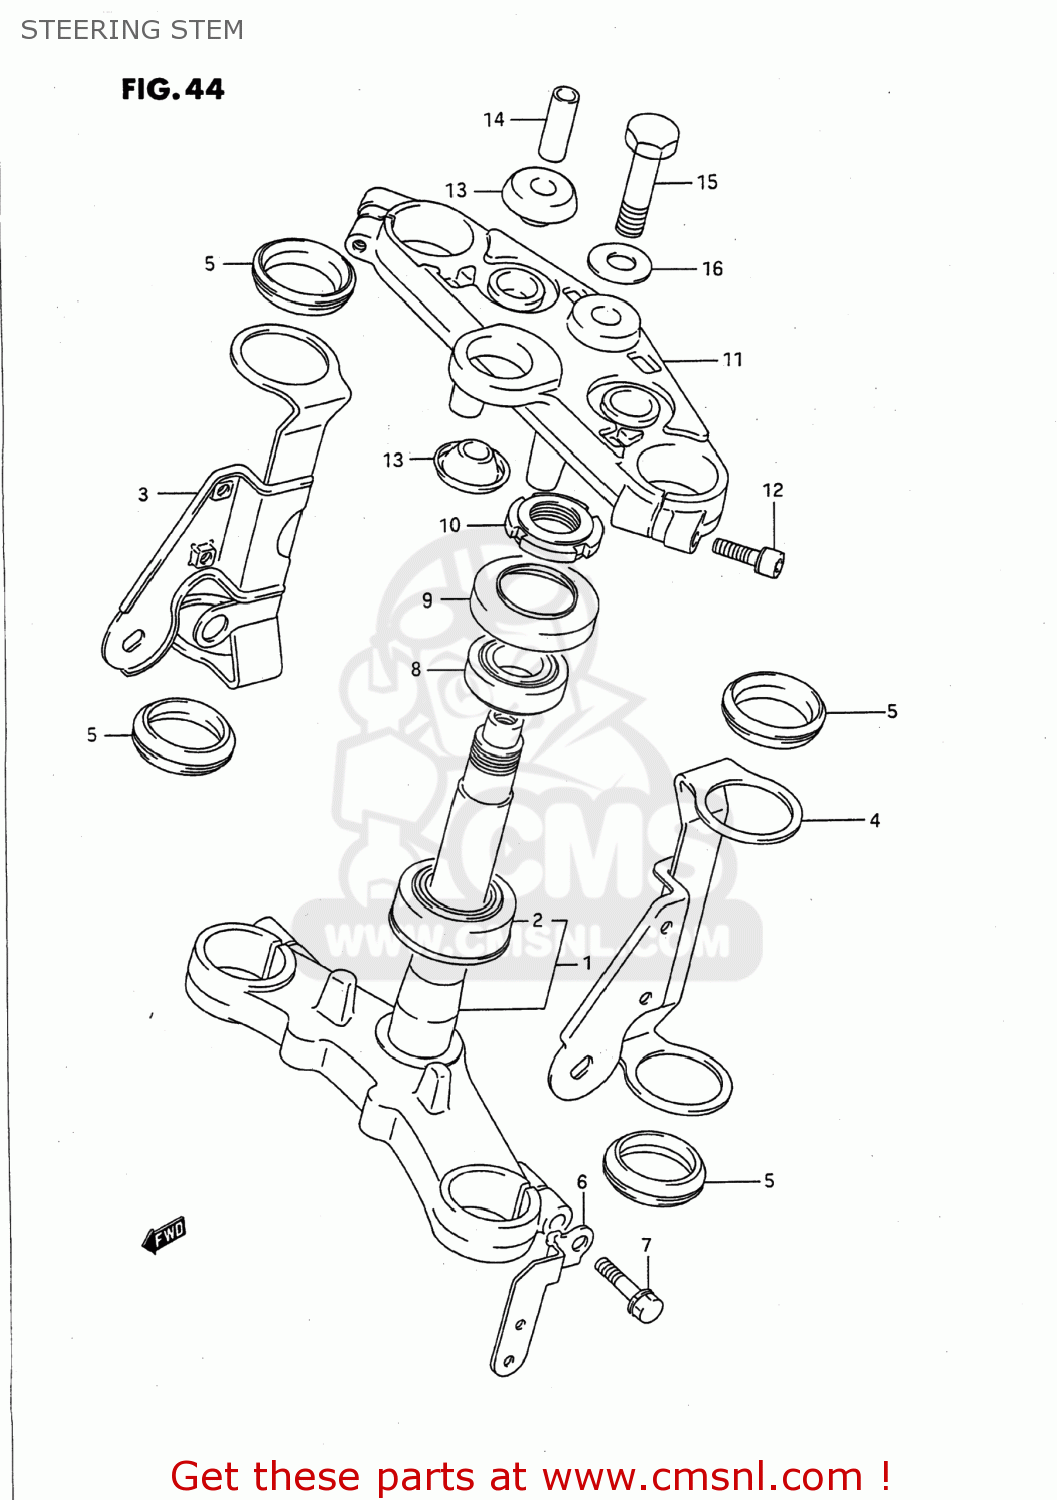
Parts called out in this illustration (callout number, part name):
1	STEM,STEERING
2	BEARING(30X55X17)
3	BRACKET,HEADLAMP,R
4	BRACKET,HEADLAMP,L
5	CUSHION,HEADLAMP BRACKET
6	BRACKET,FR SIDE RR,R
7	BOLT,STEERING STEM
8	TAPER,ROLLER BEARING
9	DUST SEAL,STEERING UPR
10	NUT,STEERING STEM(25X44X10)
11	HEAD,STEERING STEM
12	BOLT
13	CUSHION,UPR BRACKET
14	SPACER,STEERING STEM HEAD
15	BOLT
16	WASHER,STEM HEAD(10.5X30X3.2)
